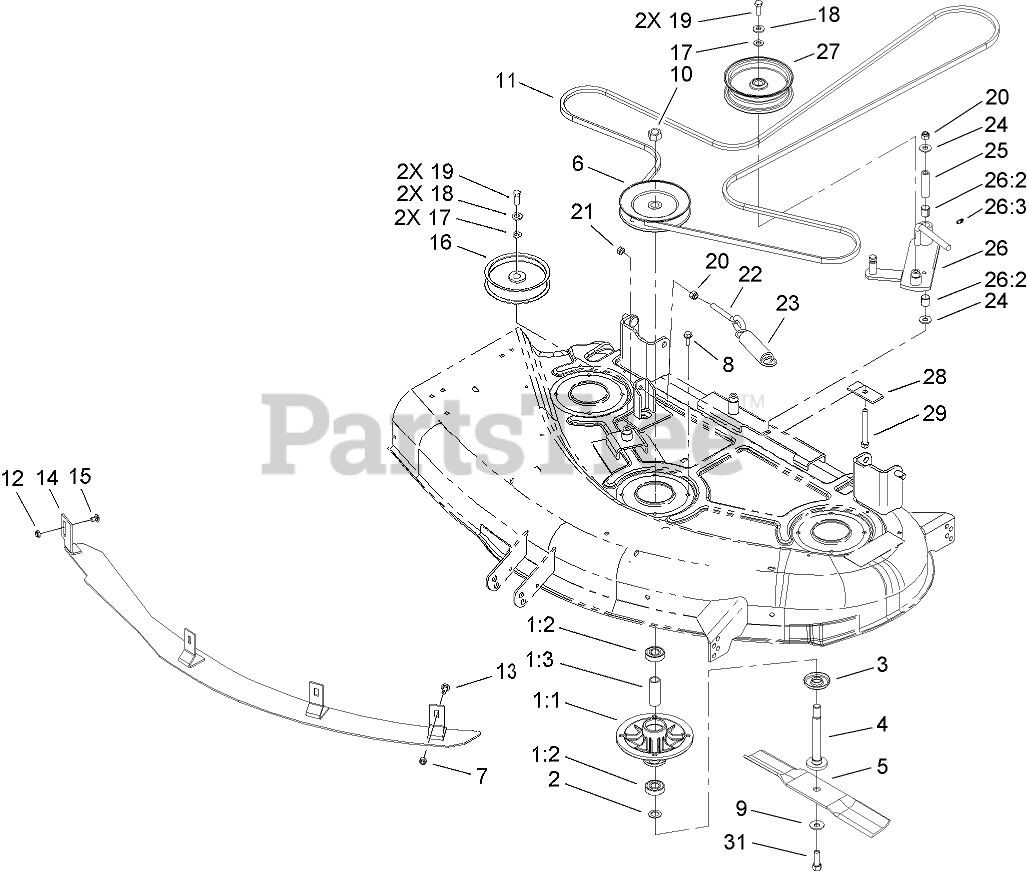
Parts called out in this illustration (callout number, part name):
1	Spindle ASM
1:1	HOUSING-SPINDLE
1:2	BEARING-BALL
1:3	SPACER
2	SPACER
3	SHIELD-BEARING
4	SHAFT-SPINDLE
6	PULLEY ASM
7	NUT-LOCK, NI
8	SCREW-TAPTITE
9	WASHER-BELLEVILLE
10	NUT-HEX
11	BELT-V
12	NUT-LOCK, NI
13	BOLT-CARR
15	SCREW-CARR
16	PULLEY-IDLER
17	WASHER-FLAT
18	WASHER-BELLEVILLE
19	SCREW-HH
20	NUT-LOCK, NI
21	NUT-HEX
22	BOLT-EYE
23	SPRING-EXTENSION
24	WASHER-HARDENED
25	BUSHING-PIVOT, IDLER
26	IDLER ARM ASM
26:2	SLEEVE-BEARING
26:3	FITTING-GREASE
27	PULLEY-IDLER, FLAT
28	SCREW-HH
29	PLATE-BOLT, RETAINER
31	SCREW-HH
